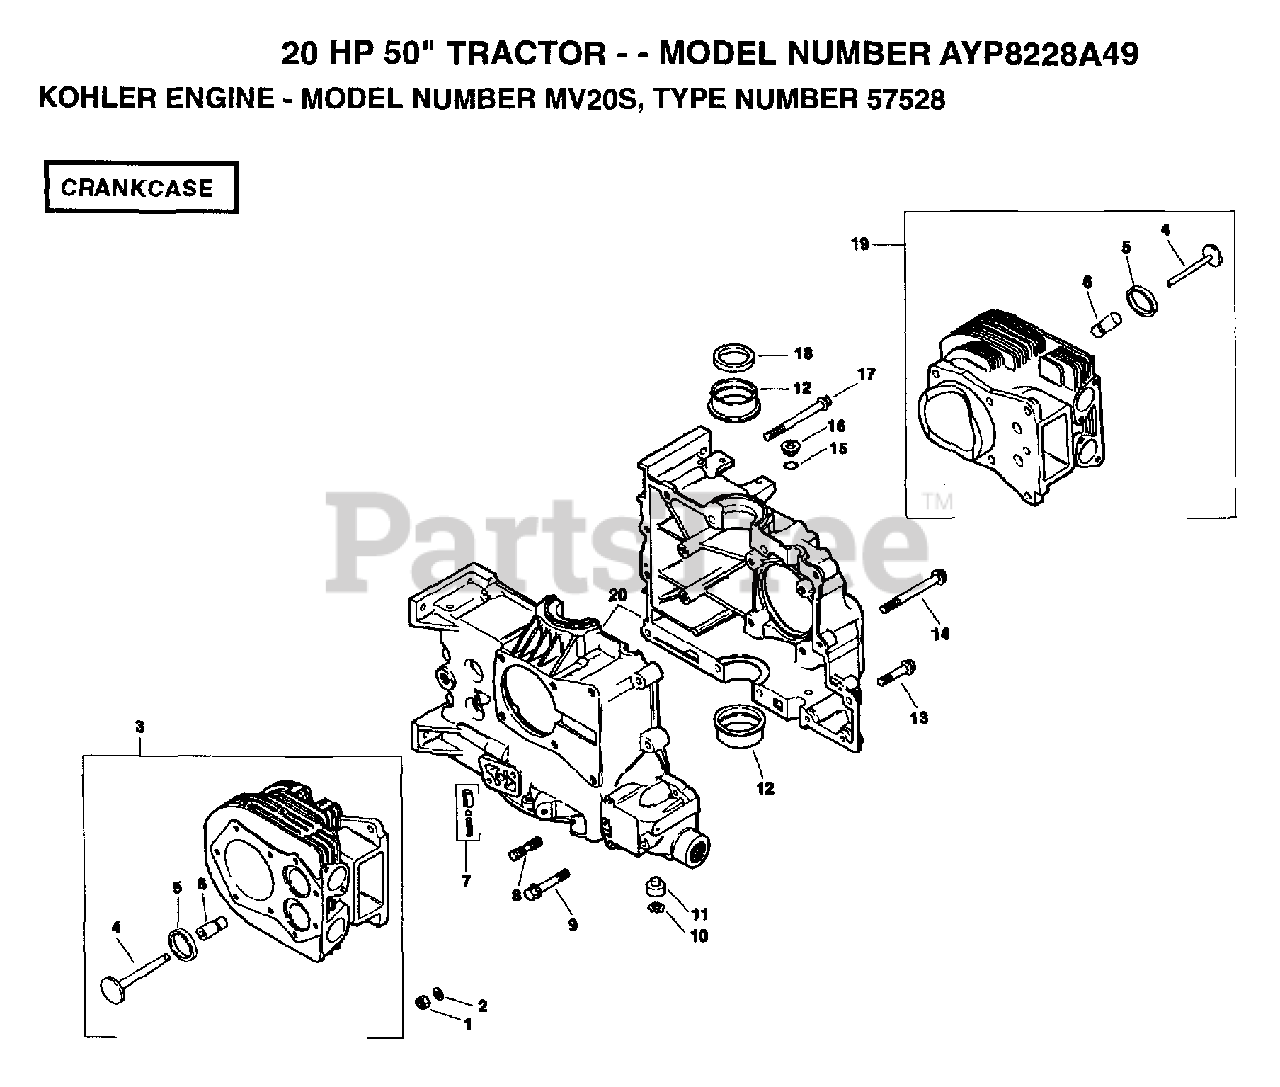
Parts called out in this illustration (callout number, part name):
3	KIT #1 CY. BARREL
4	VALVE EXHAUST
10	RING, RETAINING
19	KIT #2 CY. BARREL
